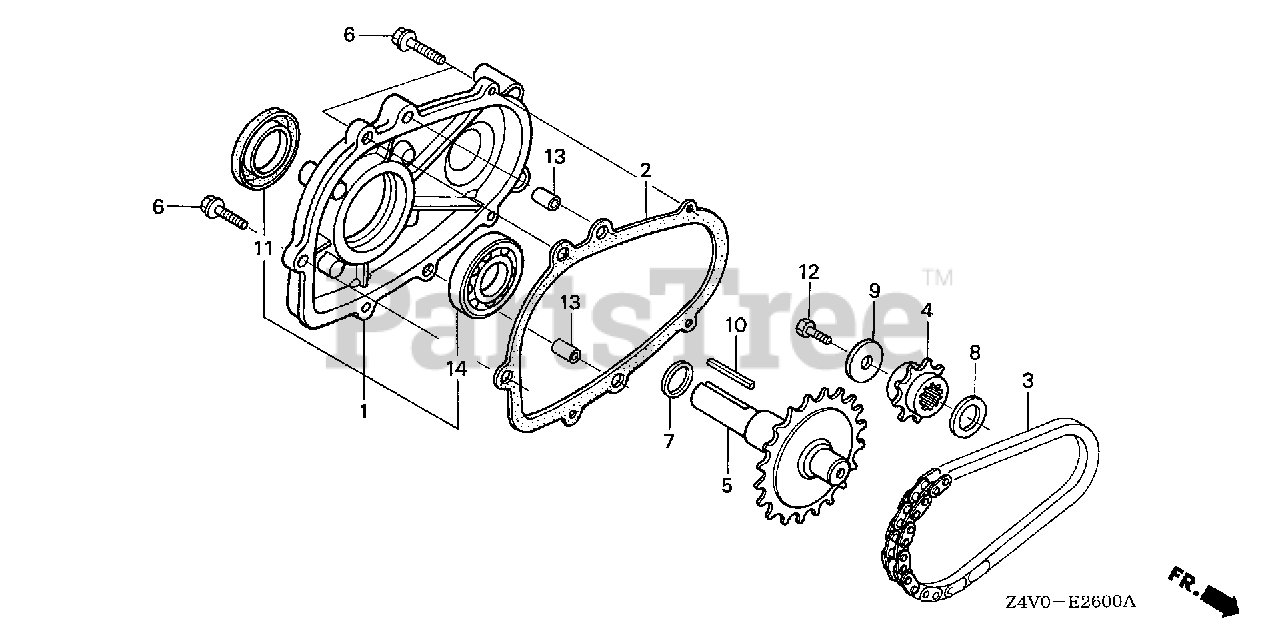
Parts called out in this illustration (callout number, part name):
1	COVER ASSY., CHAIN CASE
2	GASKET, CHAIN CASE COVER
3	CHAIN, P.T.O. DRIVE (DID317FM2-34LE)
4	SPROCKET, DRIVE
5	SHAFT, P.T.O.
6	BOLT, FLANGE (6X28) (CT200) Use up to Engine SN 1530314.
7	SPRING, THRUST
8	SPACER (20MM)
9	WASHER (8MM)
10	KEY (5X5X33)
11	OIL SEAL (25X41X6)
12	BOLT, HEX. (8X25)
13	PIN A, DOWEL (8X14)
14	BEARING, RADIAL BALL (6205)
